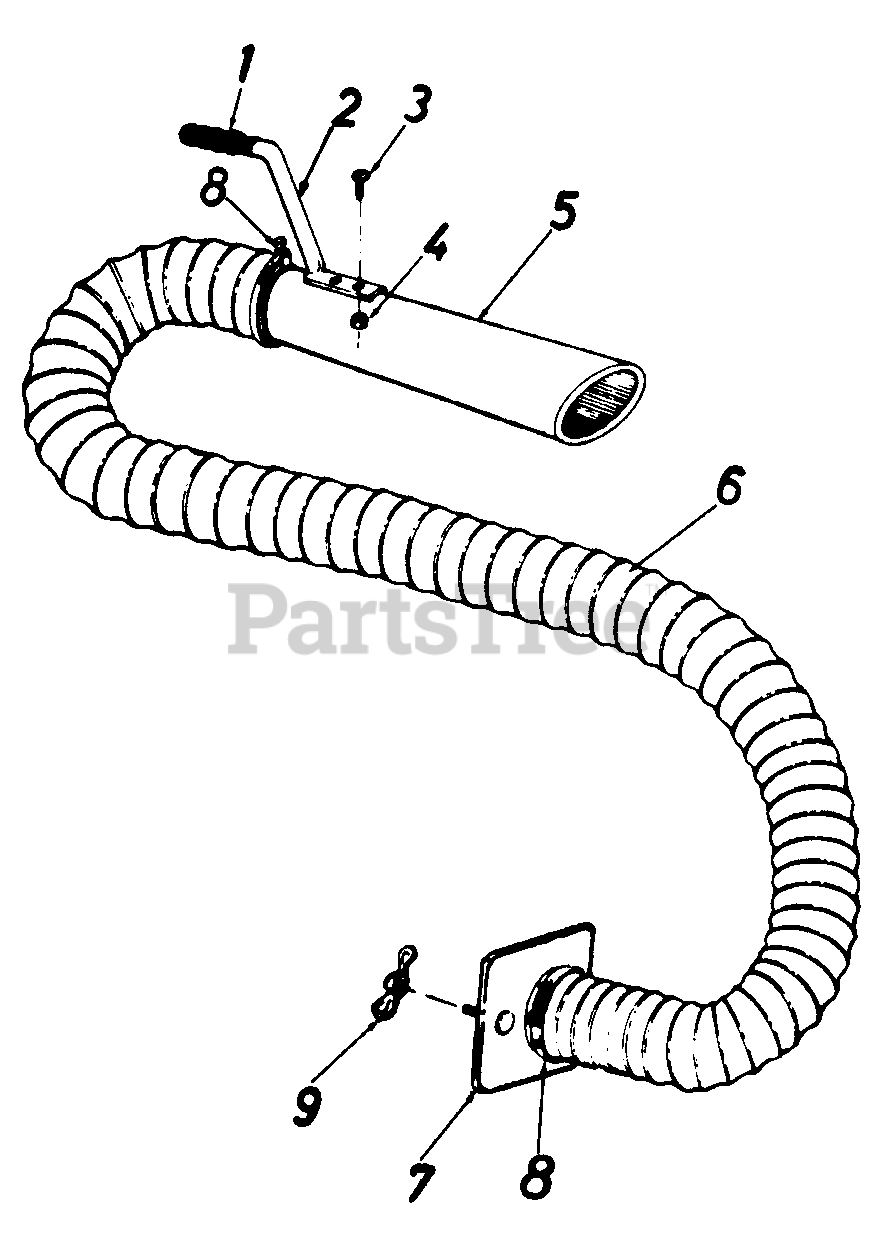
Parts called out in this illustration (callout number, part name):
1	Handle Grip
2	Handle
3	Truss Sems Scr. 10-24 x 1/2" Lg.*
4	Hex Nut 10-24 Thd.*
5	Hose Nozzle
6	Flexible Hose 4" Dia. x 10" Lg
7	Hose Adapter Plate
8	Hose Clamp - For 4" Dia. Hose
9	WingNut 1/4-20Thd.
